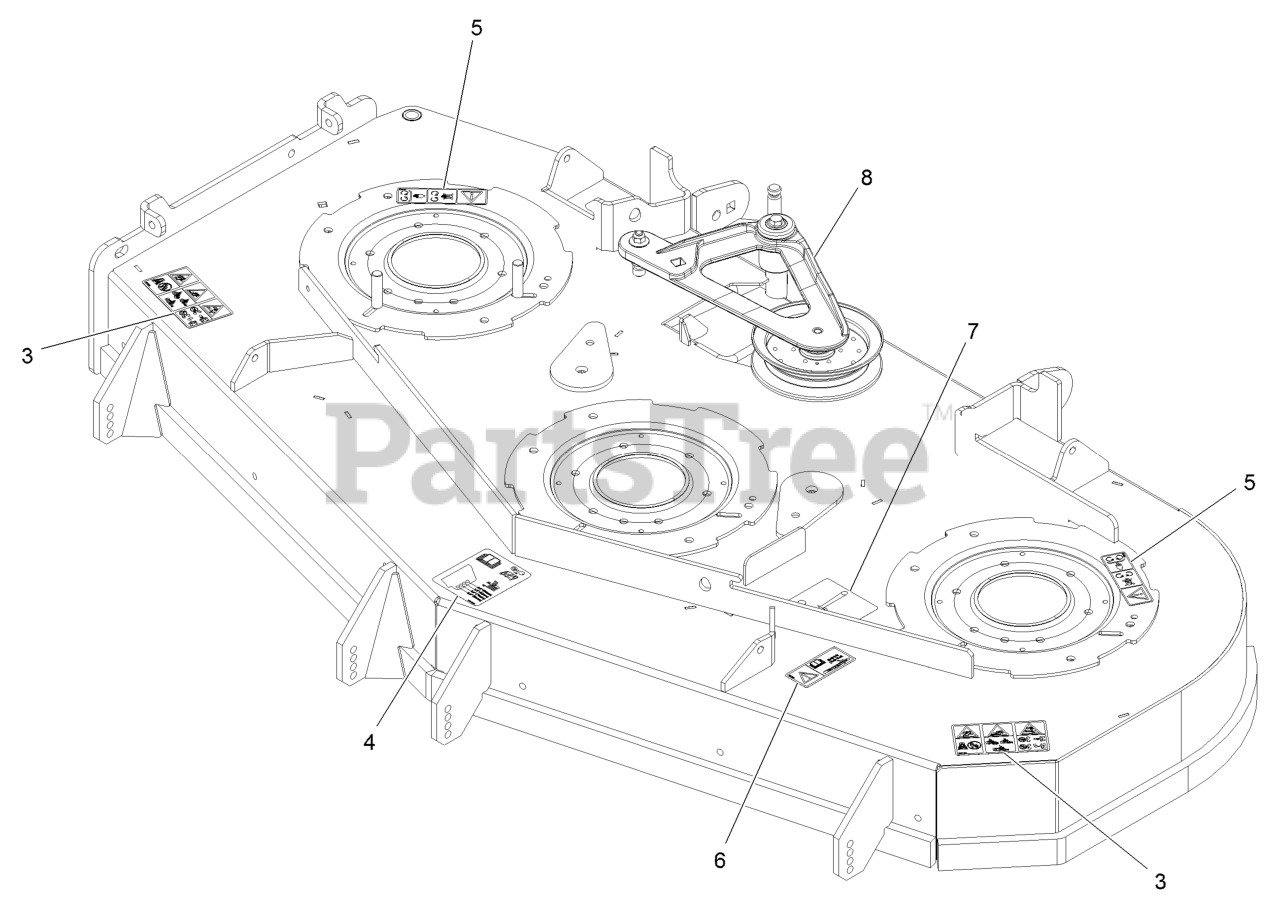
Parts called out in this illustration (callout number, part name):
3	DECAL-DANGER THROWN OBJECTS
4	DECAL-ROLLER, ANTI-SCALP
5	DECAL-COVER, MISSING
6	DECAL-BOLT TORQUE
7	DECAL-BELT ROUTING
8	DECK IDLER ASM
